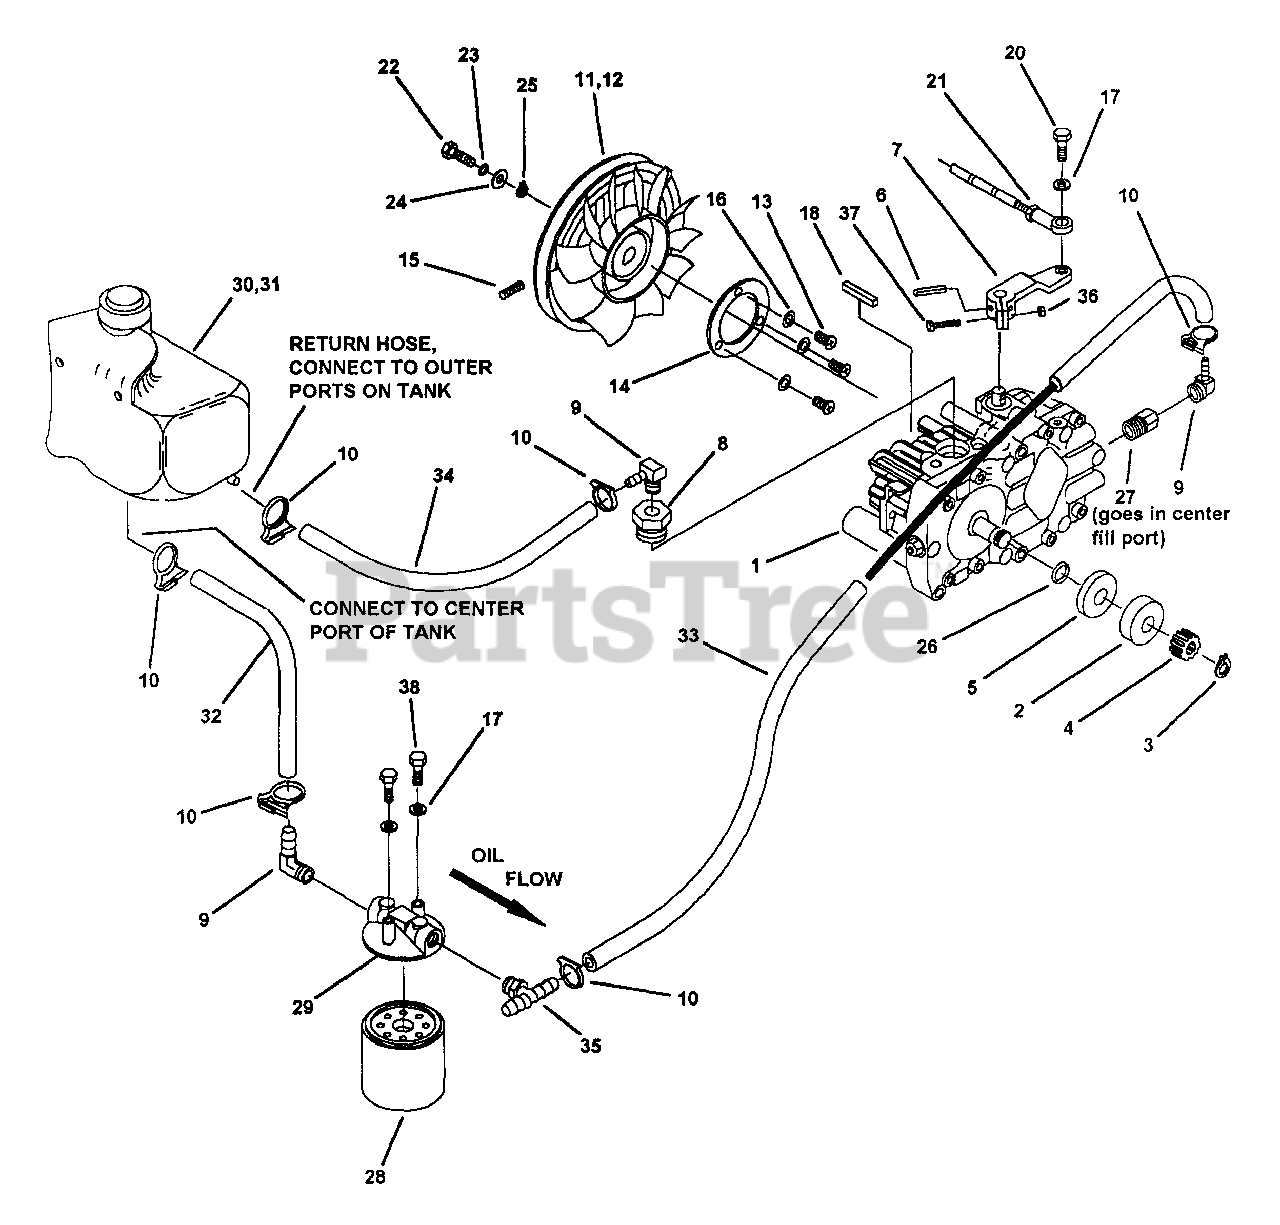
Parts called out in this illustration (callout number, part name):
1	HYDROSTAT TRANSMISSION, L.H.
1	HYDROSTAT TRANSMISSION, R.H.
2	BEARING, BALL
3	SNAP RING, EXT.
4	GEAR, 11 TOOTH
5	SPACER, BEARING
6	ROLL PIN, 5MM X 26MM
7	SHIFT ARM
8	ADAPTER, 7/8-14M TO 1/4-18F
9	HOSE BARB, 90D ELBOW, 1/4NPTM X 3/8"
10	HOSE CLAMP, 19/32-21/32, NYLON
11	PULLEY/FAN ASSEMBLY (comes with items 12, 24 & 25)
12	FAN, 7" PLASTIC; 10 BLADE CCW
13	BOLT, 1/4-20 X 1/2", GR.5
14	WASHER, 3" O.D.
15	SETSCREW, SKHD 1/4-20 X 3/4" W/NYLOC
16	LOCKWASHER, 1/4" SPLIT SPRING
17	LOCKWASHER, 1/4" SPLIT SPRING
18	KEY, 5 MM SQ. X 25 MM
20	BOLT, 1/4-20 X 3/4" GR. 5
21	NUT, 1/4-28 (COMES WITH PUSH-PULL CABLE)
22	BOLT, 6 MM X 16 MM
23	LOCKWASHER, 6MM
25	SNAP-RING INT. 15 MM
26	O-RING SEAL
27	ADAPTER, 7/16" SAE TO 1/4 NPT
28	OIL FILTER
29	FILTER BASE
30	TANK, 1.5 QT, CHARGE PUMP STYLE (comes with cap, item 31)
31	CAP, Oil Tank
32	HOSE, 6-3/4"
33	HOSE, 46", L.H.
33	HOSE, 24", R.H.
34	HOSE, 18"
35	TEE FITTING, 3/8 x 3/8 x 3/8 NPT
36	NUT, 1/4-20, NYLOC
37	BOLT, 1/4-20 X 1", GR.S
38	BOLT, 1/4-20 X 5/8", GR.5
